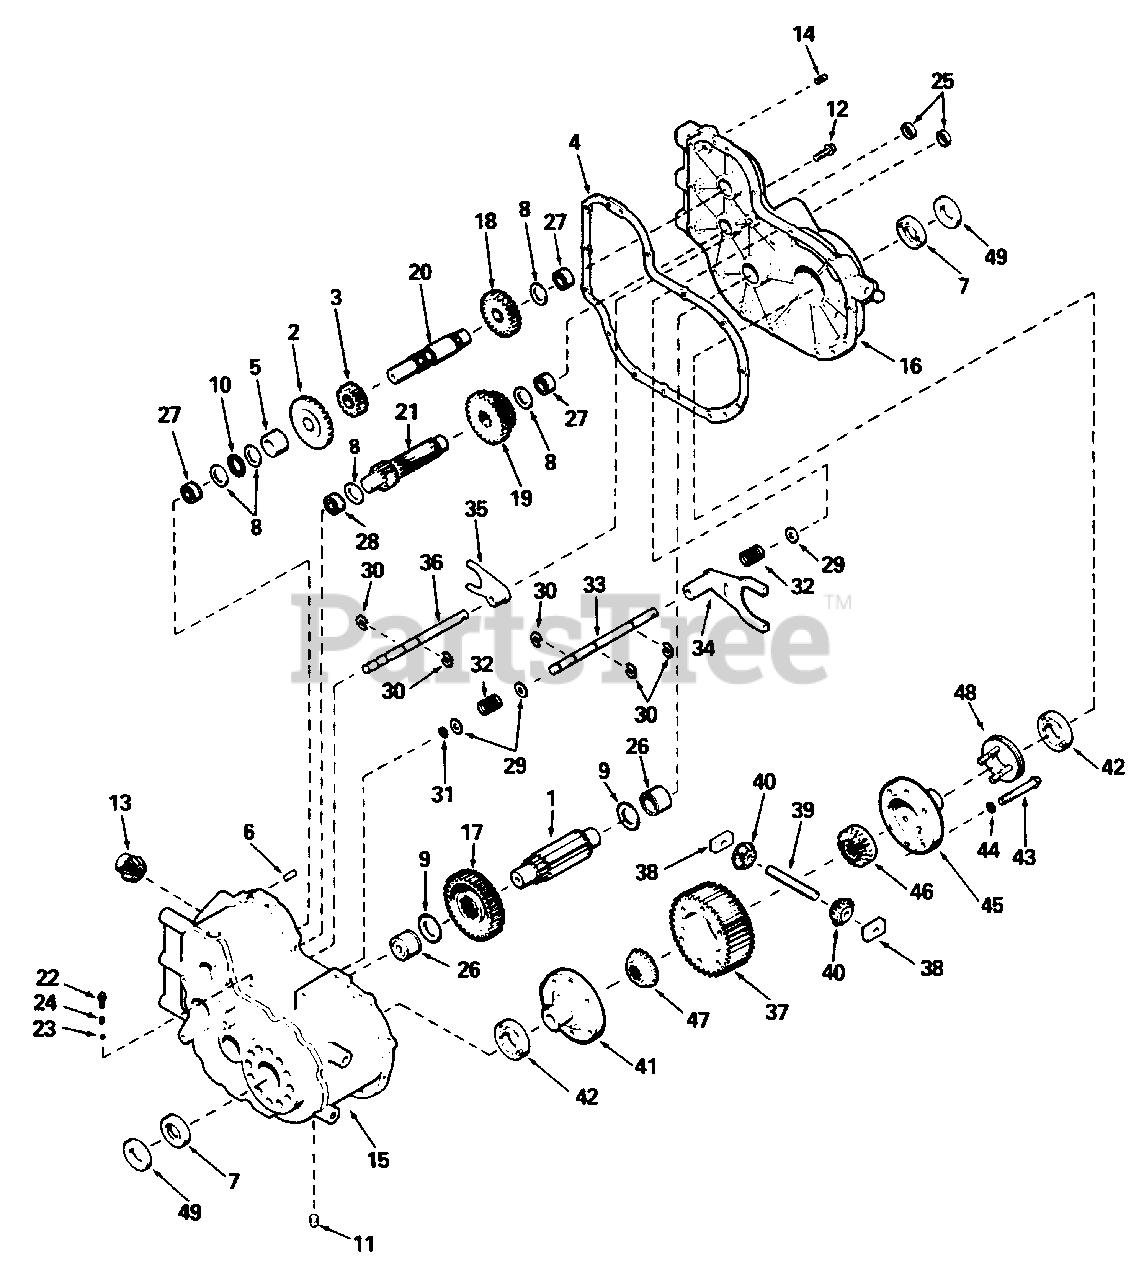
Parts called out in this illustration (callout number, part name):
1	PINION, Output
2	GEAR, Bevel (30 teeth)
3	GEAR, Spur (16 teeth)
4	GASKET, Case & Cover
5	SPACER, 1-5/8 OD x 1-1/64 ID x 55/64 thick
6	PIN, Dowel
7	SEAL, Oil
8	WASHER, Thrust, 1.542 OD x 1.007 ID x .060 thick
9	WASHER, Thrust, 2.187 OD x 1.257 ID x .060 thick
10	BEARING, Thrust
11	PLUG, Magnetic drain, 3/8-18
12	SCREW, Hex Hd. Threadforming, 5/16-18 x 1
13	PINION, Bevel
14	PLUG, Pipe, 1/8-27
15	CASE ASSY., Transaxle (Incl. Ref. Nos. 26, 27 & 28)
16	COVER ASSY., Transaxle (Incl. Ref. Nos. 26 & 27)
17	GEAR, Output (37 teeth)
18	GEAR, Spur (23 teeth)
19	GEAR, Spur (23 & 27 teeth)
20	SHAFT, Counter
21	SHAFT & GEAR, Shifter
22	SCREW, Hex Flanged Hd. 1/4-20 x 5/8
23	BALL, Steel, 3/16
24	SPRING, Shifter Fork
25	SEAL, Oil
26	BEARING, Needle
27	BEARING, Needle
28	BEARING, Needle
29	WASHER, Thrust, .917 OD x .507 ID x .060 thick
30	RING, Retaining
31	RING, Retaining
32	SPRING, Compression
33	ROD, Shift (Differential Lock)
34	FORK, Shift
35	FORK, Shift
36	ROD, Shift (Hi-Low)
37	GEAR, Ring
38	BLOCK, Drive
39	PIN, Drive
40	PINION, Bevel
41	CARRIER, Differential
42	BEARING, Ball
43	SCREW, Hex Flanged Hd., 3/8-16 x 2-3/4
44	LOCKWASHER, 3/8"
45	CARRIER, Differential
46	GEAR, Bevel
47	GEAR, Bevel
48	COLLAR ASSY., Shift
49	SPACER, 2-1/8 OD x 1-5/32 ID x 3/8 thick
